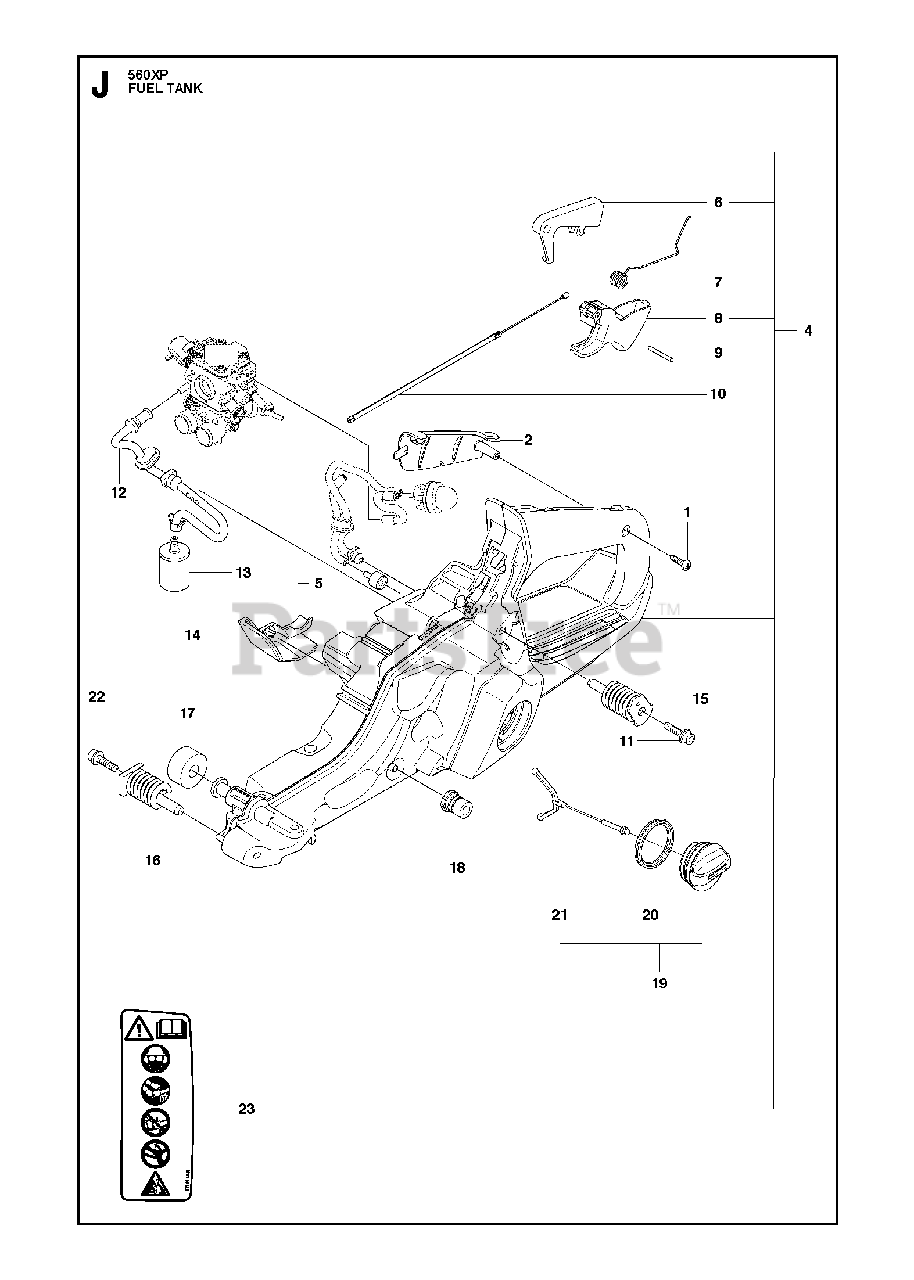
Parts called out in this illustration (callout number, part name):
2	HANDLE INSERT
4	RP FUEL TANK ASSY
5	FUEL TANK VENT
6	THROTTLE LOCKOUT
7	SPRING
8	THROTTLE
9	PIN
10	THROTTLE CABLE ASSY
12	RP FUEL HOSE
13	FUEL FILTER
15	RP ANTIVIBRATION ELEMENT
16	ANITVIBRATION ELEMENT
17	DEFLECTION LIMITER
18	LATERAL SUPPORT
19	TANK CAP
20	SEALING
21	TANK LOCK
23	DECAL
